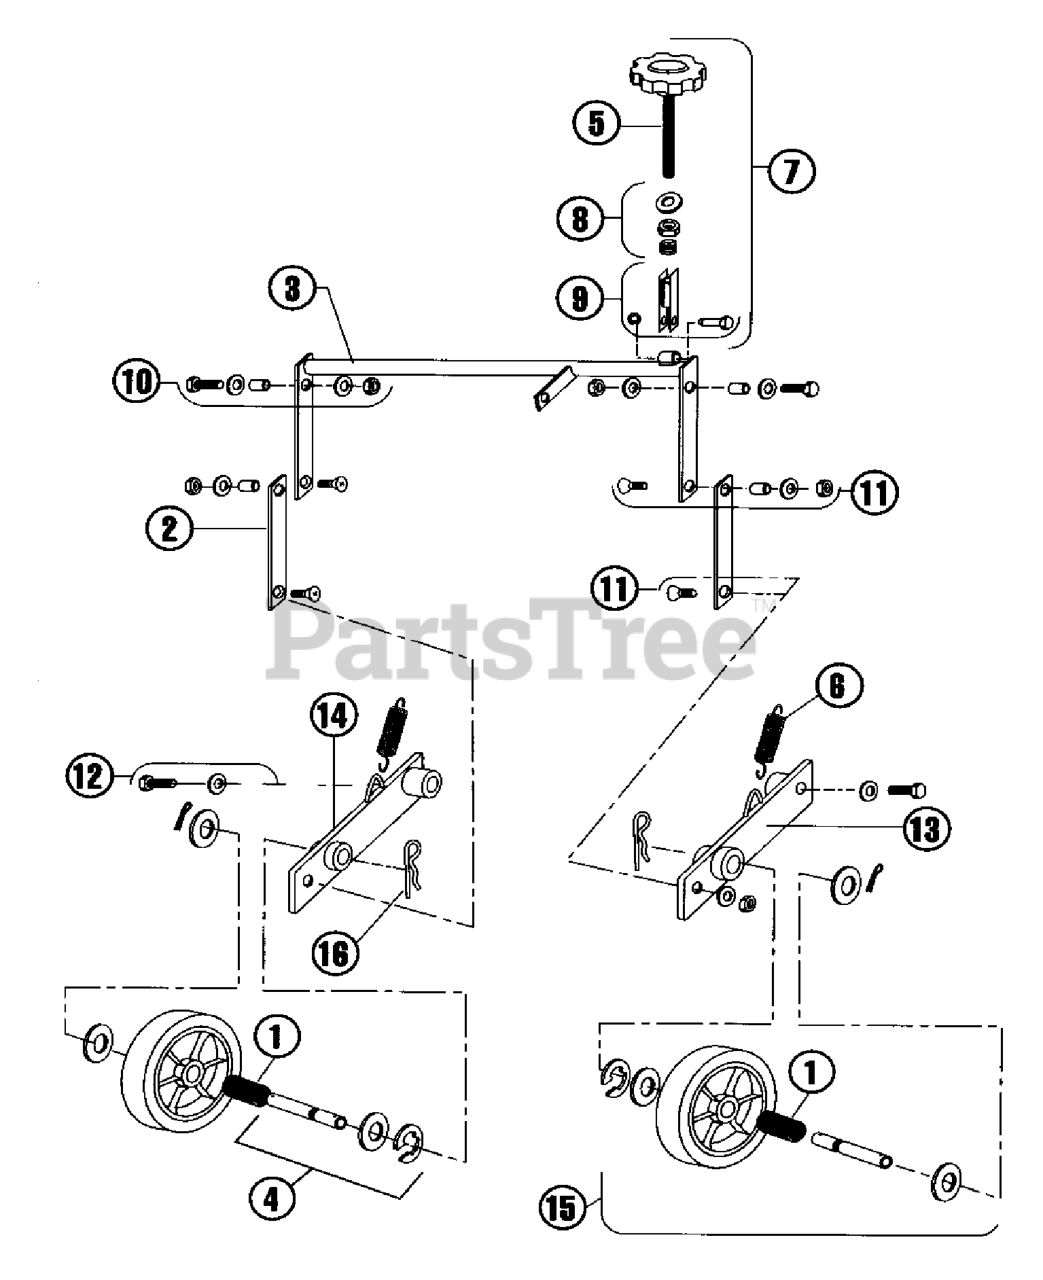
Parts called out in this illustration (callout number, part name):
1	BEARING, ROLLER
2	LIFT ARM LINK LWR ORN
3	KIT, TORQUE ARM
4	AXLE KIT
5	KNOB, DEPTH/STABILITY
6	SPRING, IDLER CAM, 3 3/4"
7	KIT DEPTH CONTROL STABILITY
8	KNOB SPRING KIT
9	BRACKET KIT
10	FASTENER KIT
11	FASTENER KIT, LINKAGE
12	FASTENER KIT
13	WHEEL ARM
14	WHEEL ARM
15	REAR WHEEL, COMPLETE
16	COTTER KEY
